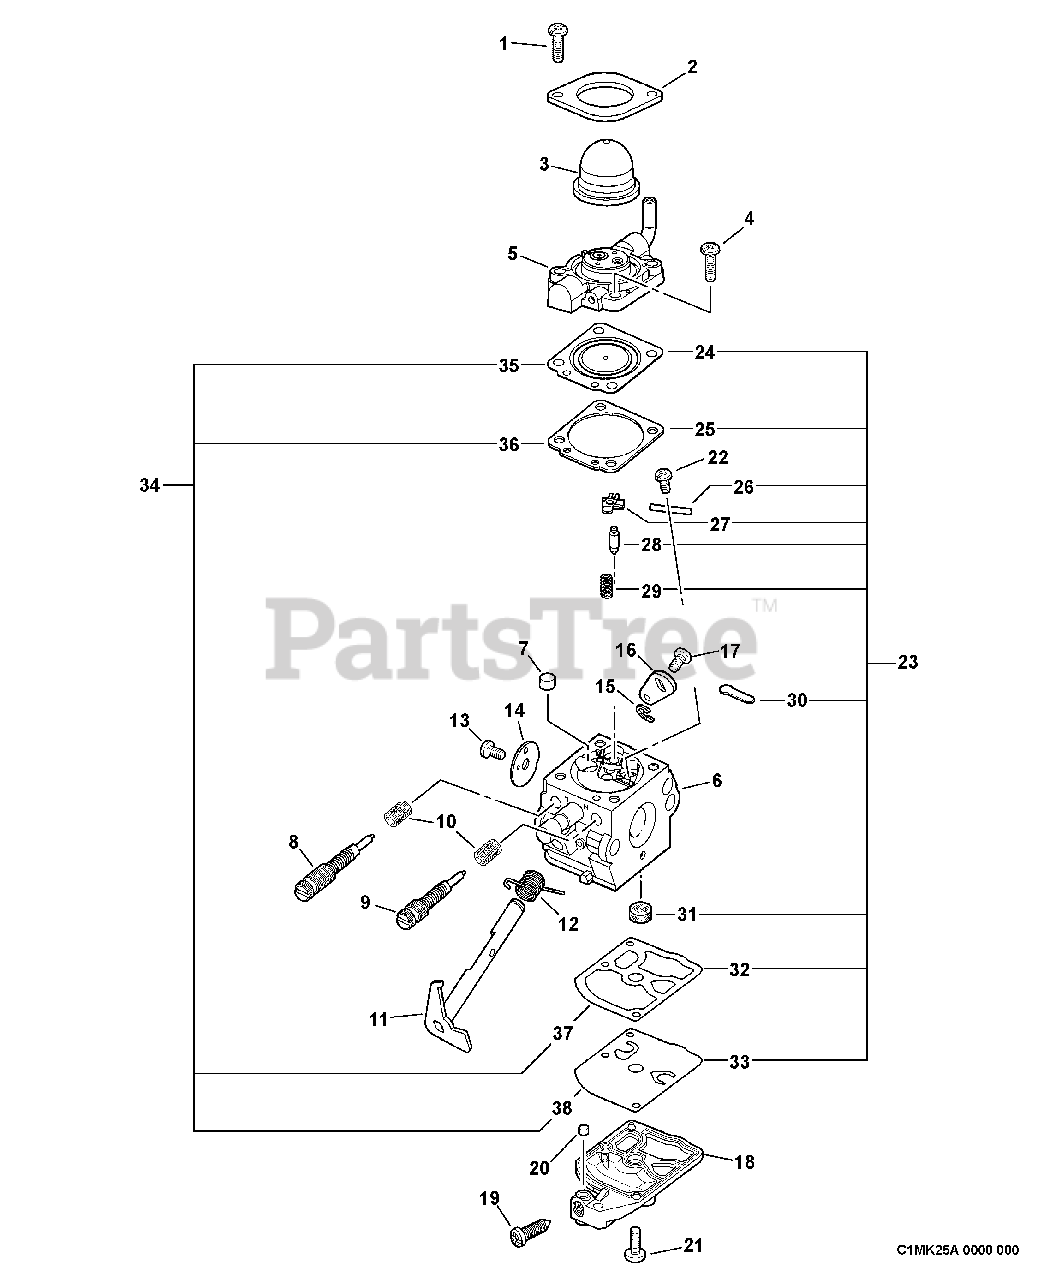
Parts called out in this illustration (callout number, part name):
2	RETAINER, PURGE BULB
3	BULB, PURGE
5	BODY ASSY, PURGE
6	BODY, CARBURETOR
7	NOZZLE, CHECK VALVE
8	SCREW
9	NEEDLE, HIGH SPEED
10	SPRING, NEEDLE
11	SHAFT, THROTTLE
12	SPRING, THROTTLE RETURN
14	VALVE, THROTTLE
16	LEVER, THROTTLE
18	COVER, PUMP
19	SCREW, IDLE ADJUST
20	PIECE, FRICTION
23	REPAIR KIT
24	DIAPHRAGM, METERING
25	GASKET, DIAPHRAGM
26	PIN, METERING LEVER
27	LEVER, METERING
28	VALVE, INLET NEEDLE
29	SPRING, METERING LEVER
30	PLUG, WELCH
31	STRAINER
32	GASKET, PUMP
33	DIAPHRAGM, PUMP
34	GASKET / DIAPHRAGM KIT
35	DIAPHRAGM, METERING
36	GASKET, DIAPHRAGM
37	GASKET, PUMP
38	DIAPHRAGM, PUMP
